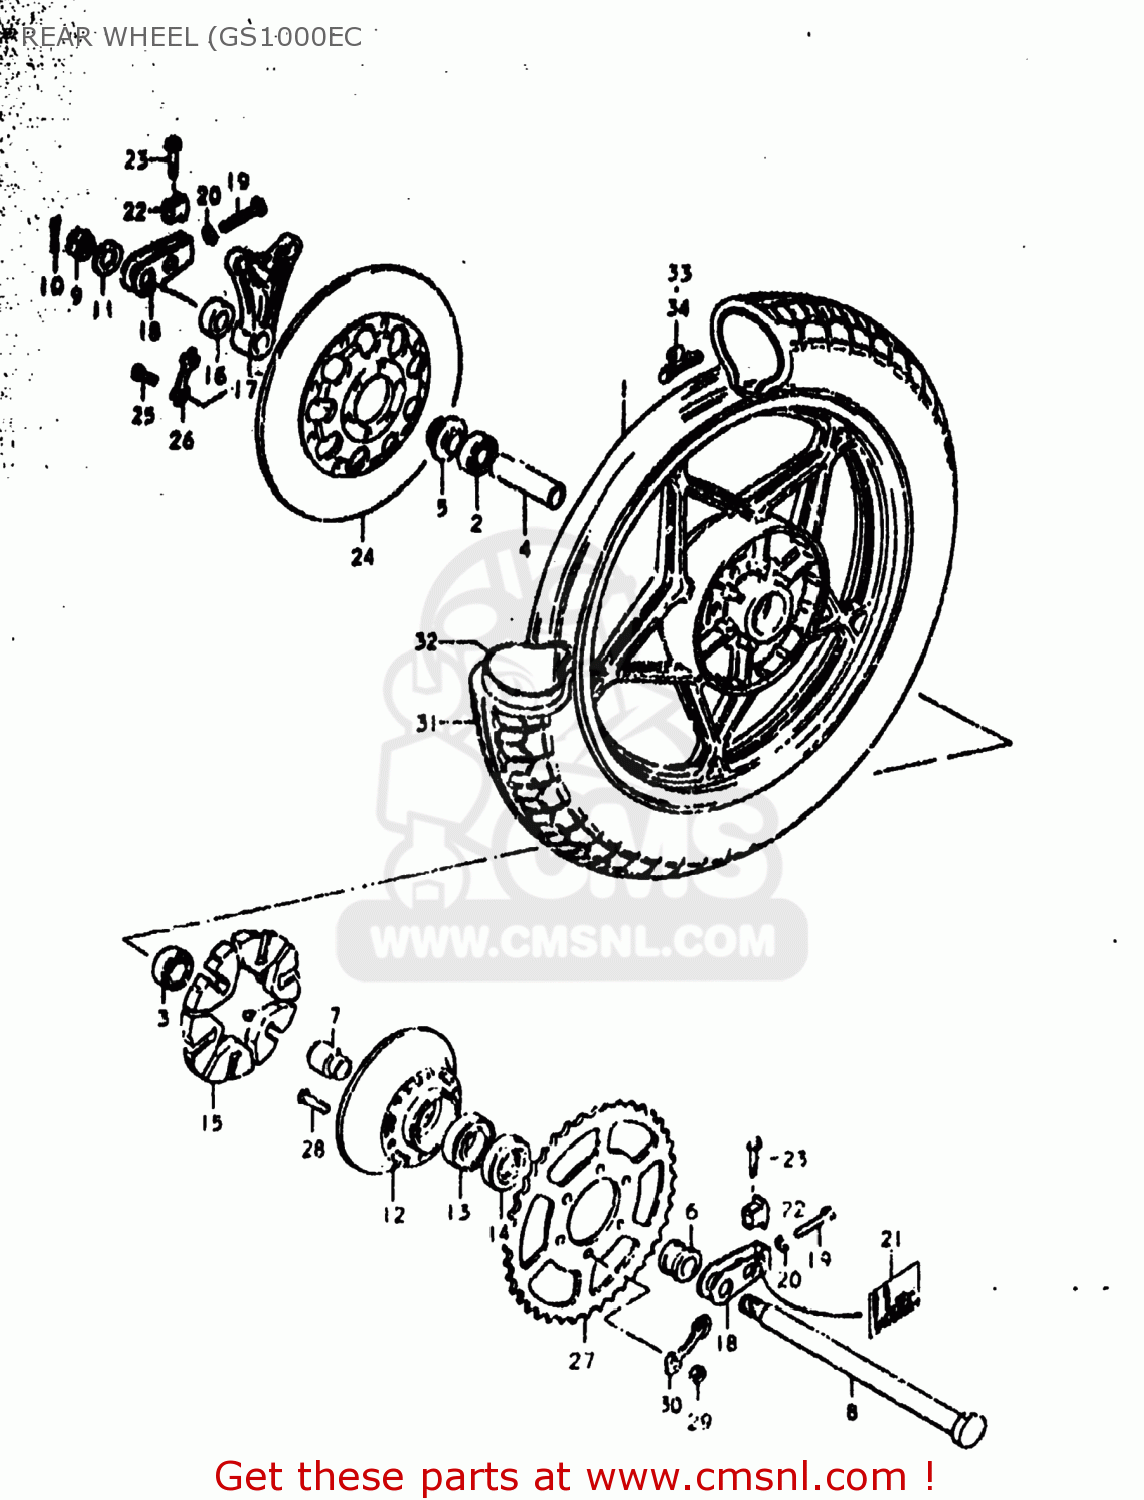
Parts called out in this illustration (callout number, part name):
1	WHEEL,REAR
2	BEARING, RH
3	BEARING, LH
4	SPACER(20.5X28X88)
5	SPACER,REAR AXLE
6	SPACER(20X33X28.3)
7	SPACER,REAR HUB BEARING
8	AXLE,REAR
9	NUT 18MM
10	PIN,COTTER
11	WASHER(19X34X4)
12	DRUM,REAR SPROCKET MOUNT
13	BEARING
14	SEAL,OIL(33X62X7)
15	ABSORBER,REAR HUB SHOCK
16	SPACER(20X38X12)
17	BRACKET,RR,CALIPER
18	ADJUSTER,CHAIN
19	BOLT
20	NUT
21	LABEL,CHAIN WEAR INDICATOR
22	SUPPORTER,CHAIN ADJUST
23	BOLT (8X40)
24	DISC,BRAKE
25	BOLT(8X30)
26	WASHER
27	SPROCKET,REAR
28	BOLT
29	NUT
30	WASHER
31	TIRE
32	TUBE ASSEMBLY,WHEEL,INNER
33	BALANCER,WHEEL
34	BALANCER,WHEEL
